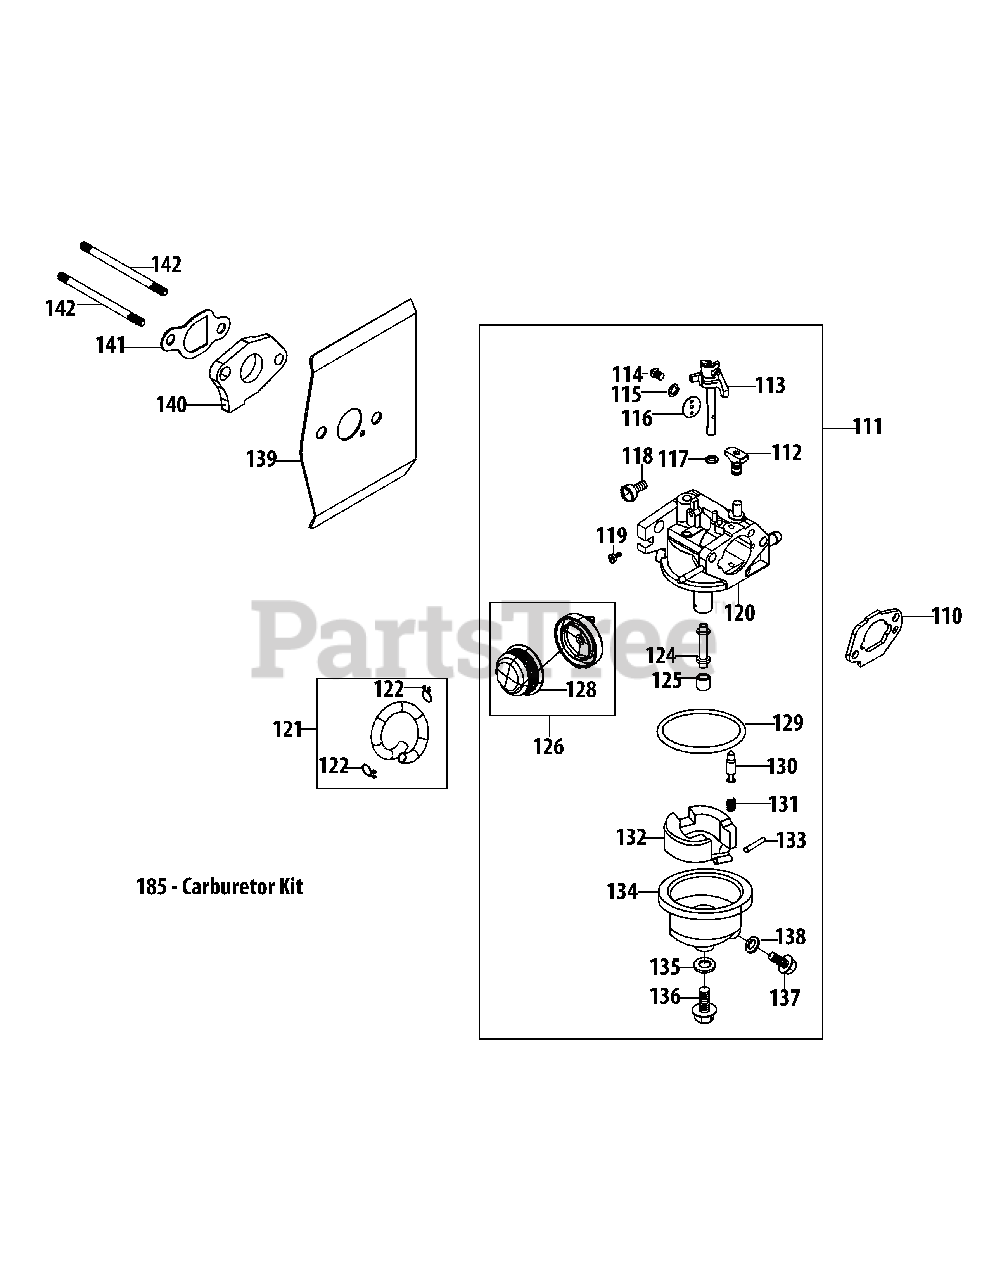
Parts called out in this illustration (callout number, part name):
110	Carburetor Gasket Plate
111	Carburetor Assembly
112	Idle Jet Assembly
113	Throttle Shaft
114	Screw M3X6 Throttle Plate
115	Throttle Plate Lock Washer
116	Throttle Plate
117	Throttle Shaft Fiber O-Ring
118	Idle Speed Adjusting Screw
119	Idle Mixture Screw
120	Carburetor Body
121	Primer Hose Assembly
122	Primer Hose Clamp
124	Emulsion Tube
125	Main Jet
126	Primer Assembly
128	Primer Bulb
129	Fuel Bowl O-Ring
130	Needle Valve
131	Needle Valve Spring
132	Float
133	Float Pin
134	Fuel Bowl
135	Fuel Bowl Gasket
136	Fuel Bowl Mounting Bolt
137	Fuel Drain Plug
138	Fuel Drain Plug Gasket
139	Carburetor Gasket
140	Carburetor Insulator
141	Carburetor Insulator Gasket
142	Carb Stud M6X92
185	Carburetor Repair Kit - Major
